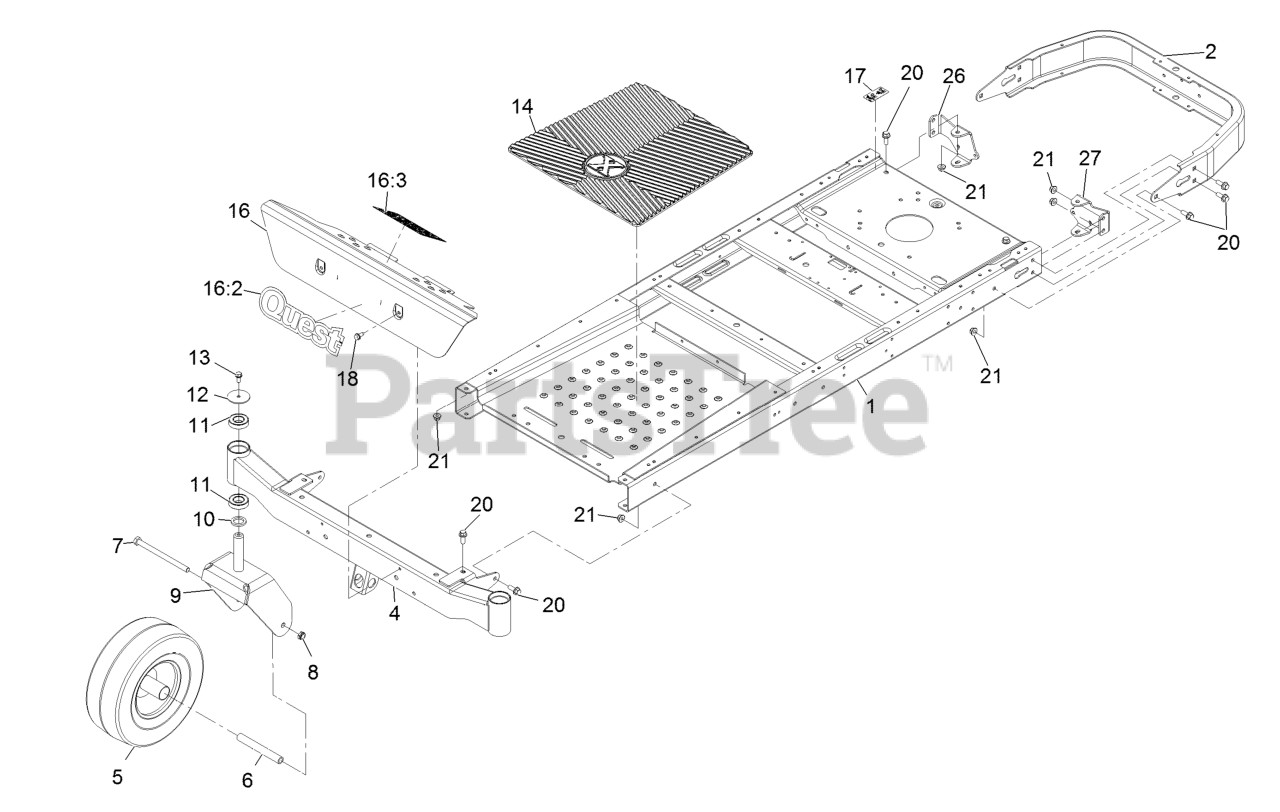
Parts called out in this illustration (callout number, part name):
2	BUMPER-REAR
4	AXLE-FRONT
5	CASTER WHEEL ASM (CST)
6	BUSHING-SPANNER
7	SCREW-HH
8	NUT-HEX
9	FORK-CASTER
10	WASHER-THRUST
11	BEARING-BALL
13	SCREW-HHF
14	MAT-FLOOR
16	FOOTREST ASM
17	DECAL-BYPASS
18	Screw-HWH 5/16-18 X 3/4 Tf
20	SCREW-HHF 3/8-16 X 1
21	NUT-HF, NI
26	MOUNT-HYDRO, REAR (RH)
27	MOUNT-HYDRO, REAR (LH)
